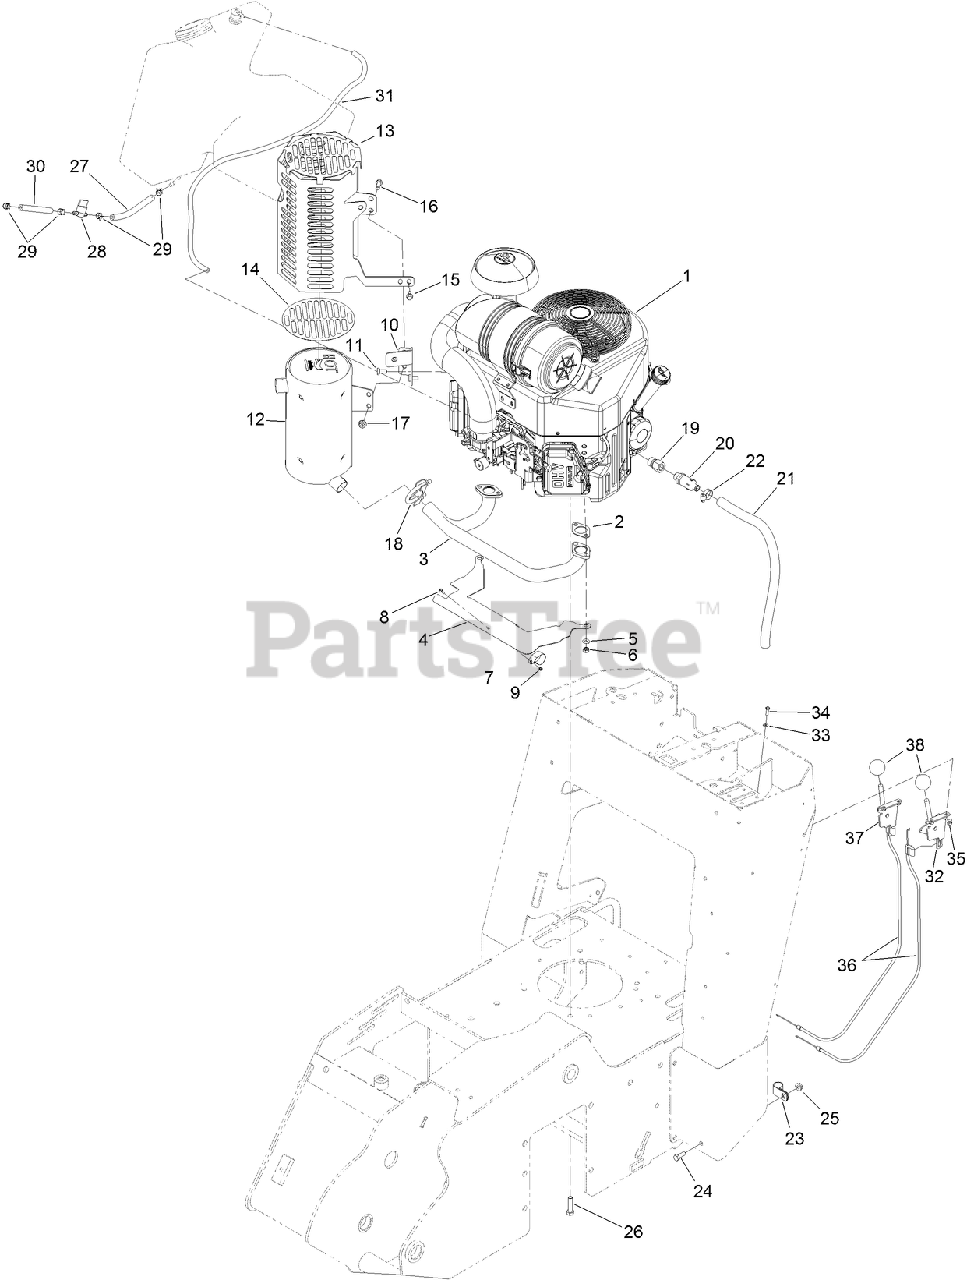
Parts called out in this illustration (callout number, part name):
1	ENGINE-KAWASAKI, FX730V
2	GASKET-EXHAUST
3	MANIFOLD, MUFFLER
4	PLATE-SHIELD, HEAT
5	WASHER-SPRING
6	NUT-HEX
8	SCREW-PAN
9	NUT-HEX
10	BRACKET-MOUNT, MUFFLER
11	SCREW-HH
12	MUFFLER
13	GUARD-MUFFLER
14	FOIL-GUARD
15	SCREW-HHF
16	SCREW-HH
17	NUT-HF
18	CLAMP-MUFFLER
19	ADAPTER
20	VALVE-DRAIN, OIL
21	HOSE-VENT
22	CLAMP-HOSE
23	CLAMP-R
24	SCREW-HH
25	NUT-HF
26	SCREW-HH
27	HOSE-FUEL
28	VALVE-FUEL
29	CLAMP-HOSE
30	HOSE-FUEL
31	HOSE-VENT, TANK
32	LEVER-CONTROL
33	WASHER-FLAT
35	NUT-LOCK, NI
36	CABLE-CONTROL
37	LEVER-CONTROL
